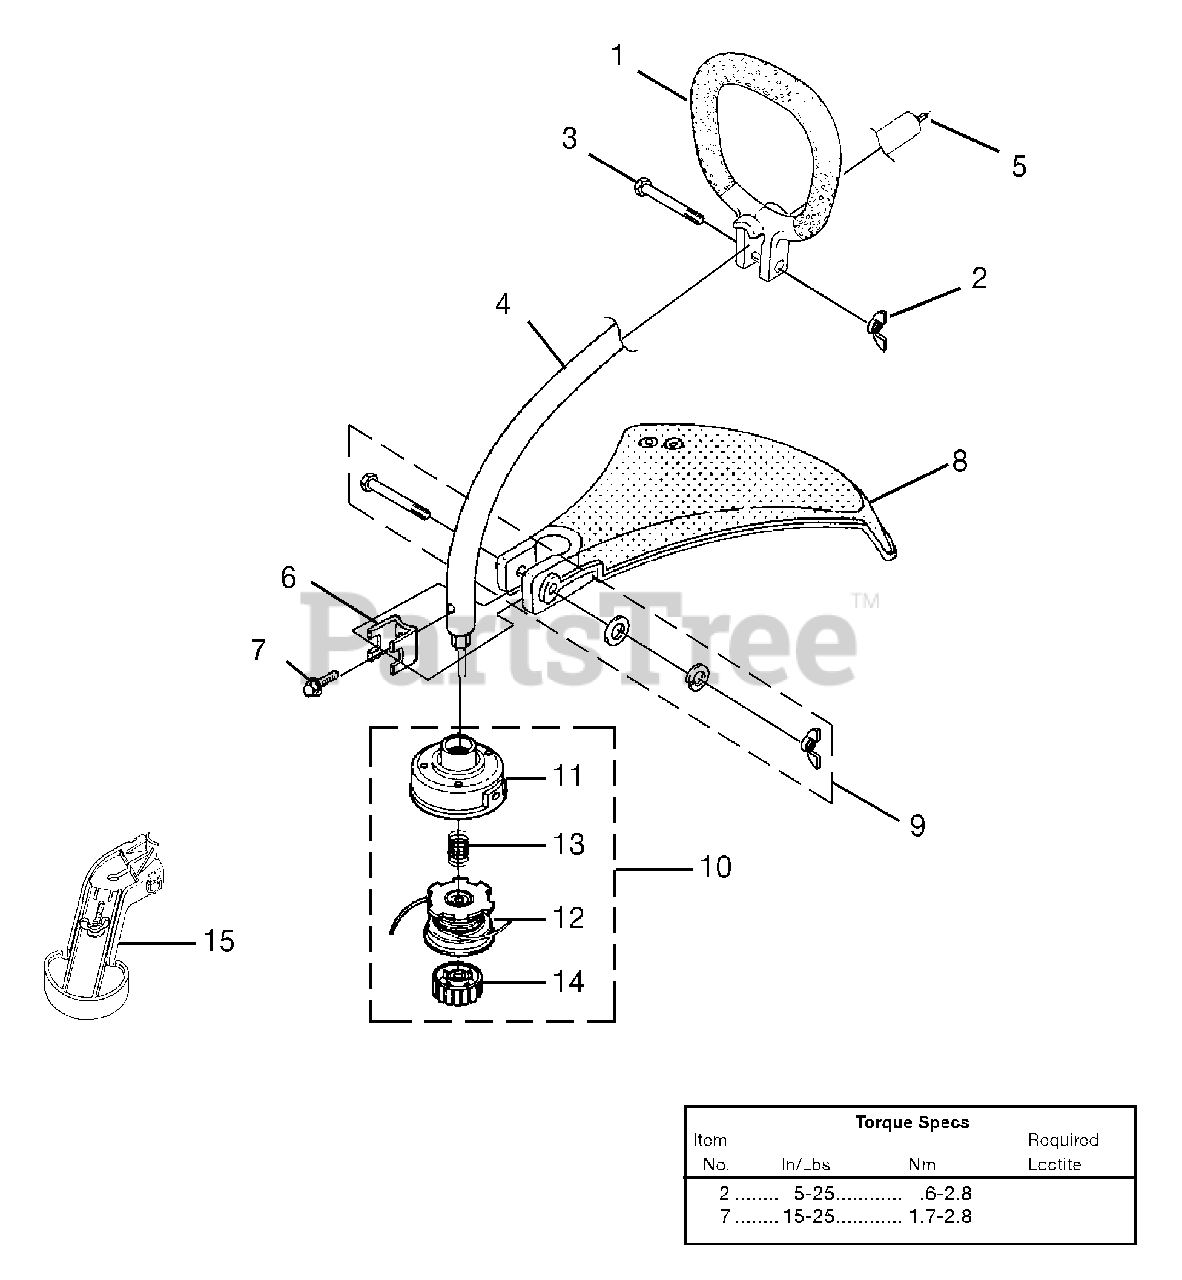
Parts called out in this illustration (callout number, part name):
1	HANDLE-Front
2	NUT-Wing, Washer Faced (1/4-20)
3	SCREW-Cap Hex Hd.
4	DRIVESHAFT HOUSING ASSY.
5	SHAFT-Flexible
6	CLAMP
7	SCREW-Sems Hex Hd. (#10-24 X 3/8")
8	DEFLECTOR-Grass
9	FASTENER KIT
10	STRINGHEAD-Complete
11	HOUSING & EYELET (Dual Line)
12	SPOOL & STRING (.080" Line)
13	SPRING-Compression
14	RETAINER-Spool (RH Thread, Black)
15	EDGER GUIDE (Trim 'n Edge Model)
